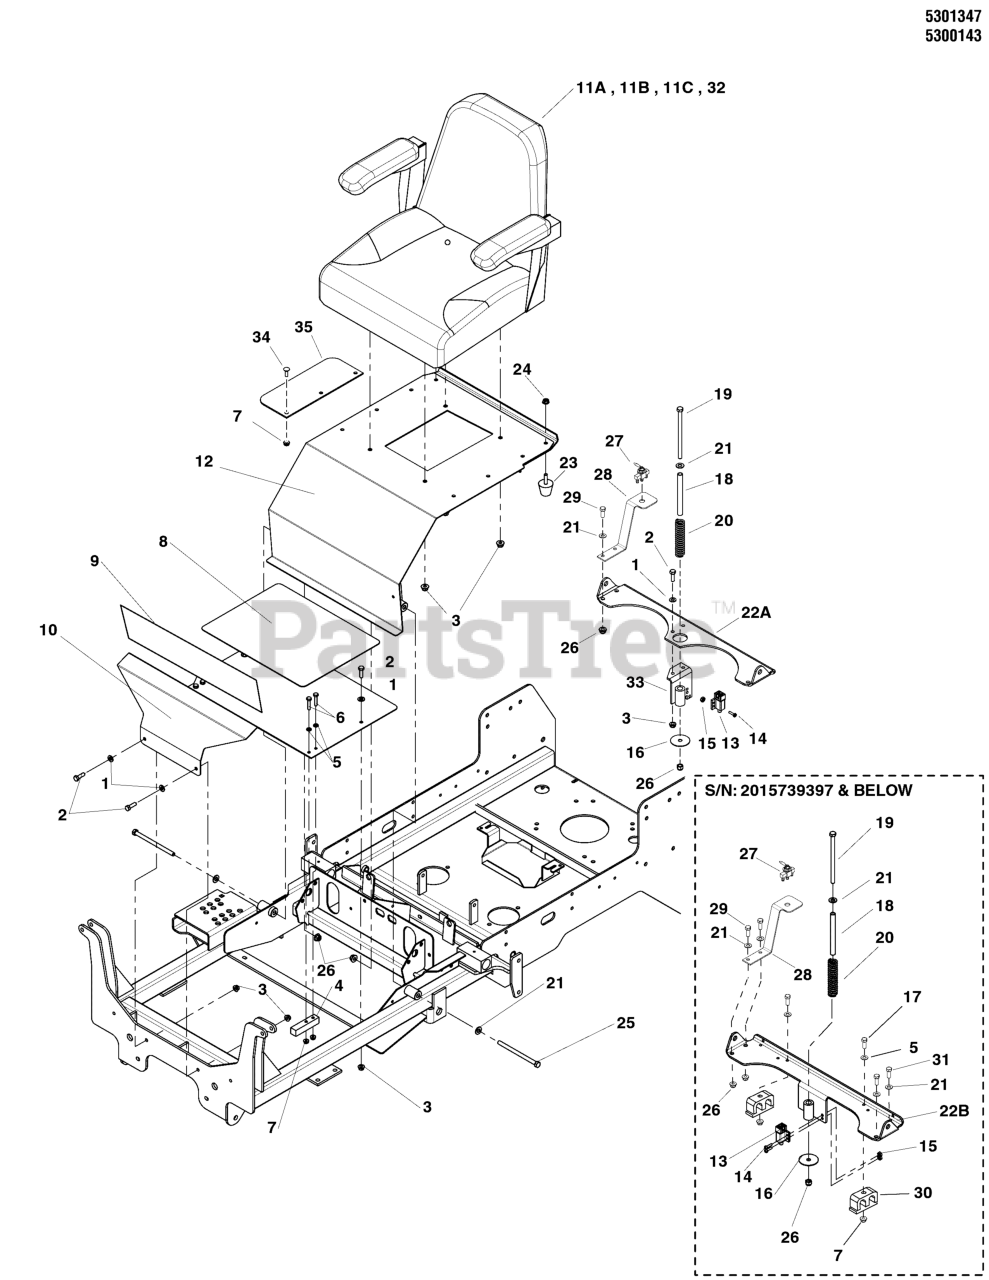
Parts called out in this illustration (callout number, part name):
1	WASHER, 5/16" SAE
2	BOLT, 5/16-18 X 1" GD5 YZ
3	NUT, 5/16-18 HEX NYLOCK FLANGE
4	BLOCK, DECK LIFT SUPPORT
5	WASHER, 1/4 SAE
6	BOLT, 1/4-20 X 1-1/4" GD5
7	NUT, 1/4-20 HEX NYLOCK FLANGE
8	SAFETY WALK, 11.50 X 15.00
9	SAFETY WALK, 8.00 X 15.00
10	PLATE, FLOOR, IS2000 - RED
12	SEAT PLATE W/DECALS, IS2000Z
13	SWITCH PLUNGER N.C. / N.C.
14	SCREW, #10-24 X 1/2" RD PHILLIPS
15	NUT, #10-24 HEX
16	WASHER, .39 X 2.00 X X .14
17	BOLT, 1/4-20 X1 1/2"
18	SPACER, .38 X .50 X 5.06
19	BOLT, 3/8-16 X 6" GD5 CZ
20	SPRING, .688 ID X .130 WIRE DIA 4.25
21	WASHER, 3/8 SAE
23	BUMPER, RUBBER 5/16-18
24	NUT, 5/16-18 HEX SERRATED FLANGE (SMALL)
25	BOLT, 3/8-16 X 5-1/2" GD5 CZ
26	NUT, 3/8-16 HEX NYLOCK FLANGE
27	VALVE, FUEL, STR. OUTLET
28	MOUNT, FUEL SELECTOR SWITCH - BLK
29	BOLT, 3/8-16 X 1" GD5 CZ
30	CLAMP, 1/2" HOSE, DOUBLE, PLASTIC
31	BOLT, 3/8-16 X 1-1/4" GD5 CZ
32	SEAT, SUSP TYPE
33	BRACKET, SPRING SWITCH
34	BOLT,1/4-20X0.750,GR5,STD NECK,SQ,ZC/CL
35	PLATE, SEAT, RUBBER FLAP
